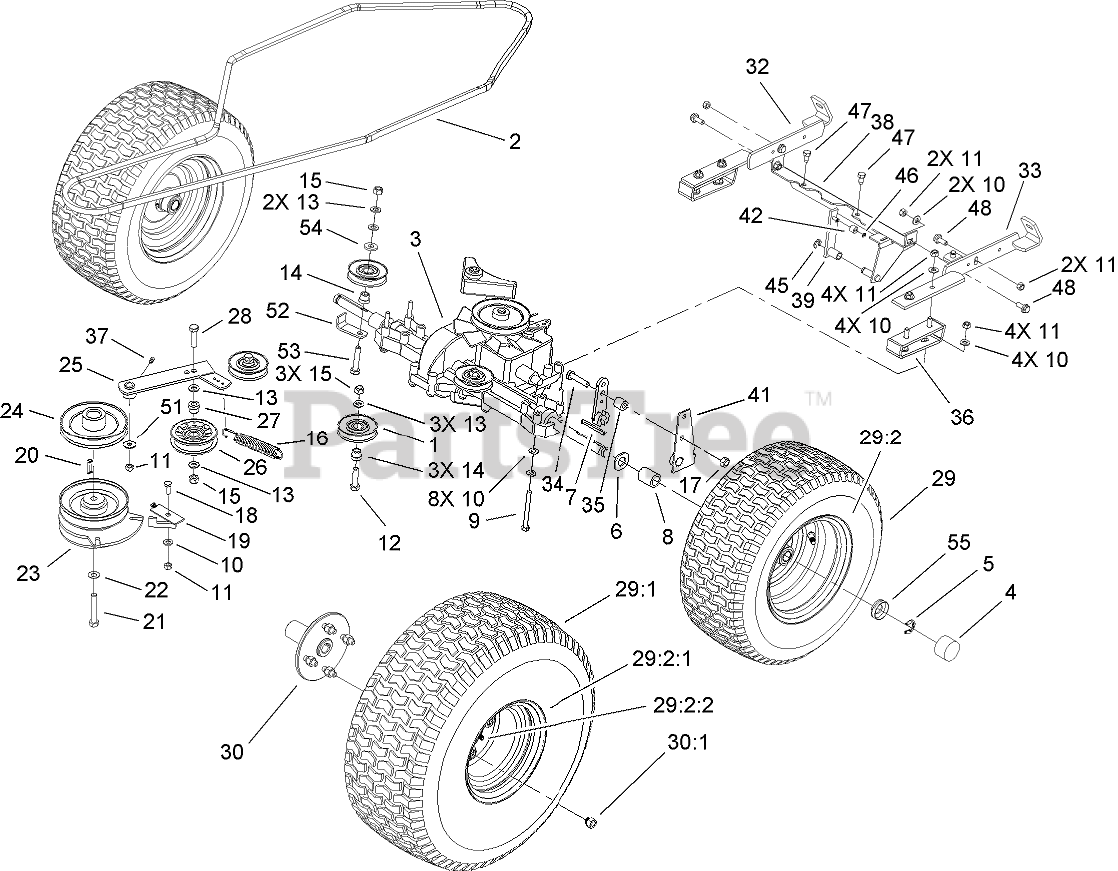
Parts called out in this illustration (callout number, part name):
1	PULLEY-IDLER
2	V-BELT-TRACTION
3	TRANSMISSION
4	CAP-HUB
5	CLIP-SPRING
6	WASHER
7	KEY-SQUARE
8	SPACER-AXLE
9	SCREW-HH
10	WASHER-PLAIN
11	NUT-LOCK, NI
12	SCREW-HH
13	WASHER-FLAT
14	BUSHING-IDLER
15	NUT-LOCK, NI
16	SPRING
17	NUT-LOCK, NI
18	SCREW-HH
19	RETAINER
20	KEY-SQUARE
21	SCREW-HH
22	WASHER-SPRING, BELLEVILLE
23	CLUTCH-ELECTRIC
24	PULLEY-ENGINE
25	ARM-IDLER
26	PULLEY-IDLER
27	BUSHING-IDLER
28	SCREW-HH
29	Tire and Wheel ASM
29:2	WHEEL ASM
29:2:1	Rim
29:2:2	Valve-Tire
30	HUB-WHEEL
30:1	NUT-LUG
32	Bracket-Right
33	Bracket-Left
34	SCREW-HH
35	SLEEVE
36	Plate-Reinforcing
37	FITTING-GREASE
38	Bar ASM
39	Arm-Switch
42	Roller
45	Stirrup
46	STIRRUP
47	SCREW-THREAD FORMING
48	SCREW-HEX
51	WASHER-PLAIN
52	RETAINER-BELT
53	SCREW-HH
54	WASHER-FLAT
55	RETAINER-CAP, HUB
